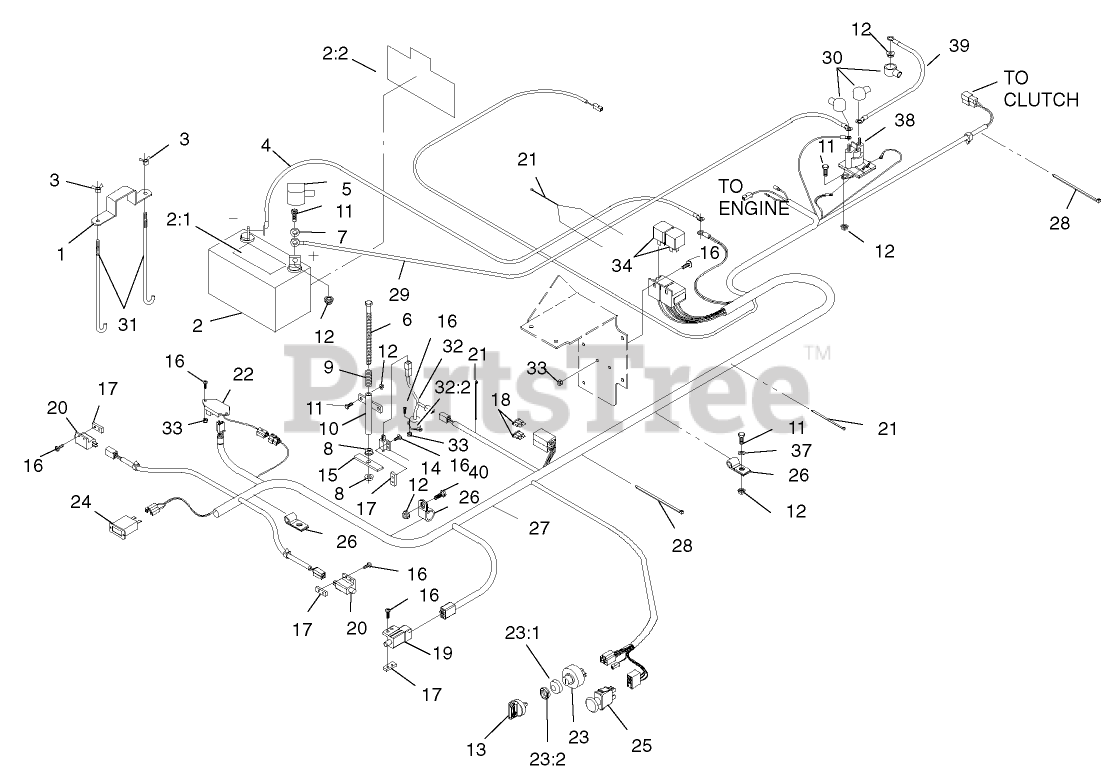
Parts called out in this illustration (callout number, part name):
1	STRAP-HOLDDOWN
2	BATTERY
2:1	Decal-Battery
2:2	Decal-Battery
3	WINGNUT
4	WIRE-GROUND
5	INSULATOR-BATTERY
6	SCREW-HH
7	WASHER-FLAT
8	NUT-HF
9	SPRING-SWITCH, SEAT
10	MOUNT-SPRING, SEAT
11	SCREW-HH
12	NUT-HF
13	KEY-IGNITION
14	SWITCH-CLOSED, NORMALLY
15	PLATE-SWITCH, SEAT
16	SCREW-PPH
17	PLATE-TAPPED
18	FUSE-BLADE TYPE, 20 AMP
19	SWITCH
20	SWITCH-OPEN, NORMALLY
21	TIE-CABLE
22	MODULE-DELAY, SEAT
23	Key Switch ASM
23:1	WASHER-TOOTH, INTERNAL
23:2	NUT-HH
24	METER-HOUR
25	SWITCH-DELTA
26	CLIP-LOOM
27	Harness-Wire
28	TIE-PLASTIC
29	WIRE-STARTER
30	INSULATOR-SOLENOID
31	BOLT-HOLDDOWN
32	TILT SWITCH ASM
32:2	DECAL-SWITCH, MERCURY
33	NUT-LOCK, NI
37	WASHER-FLAT
38	SWITCH-SOLENOID
39	CABLE-STARTER, POSITIVE
40	SCREW-HH
